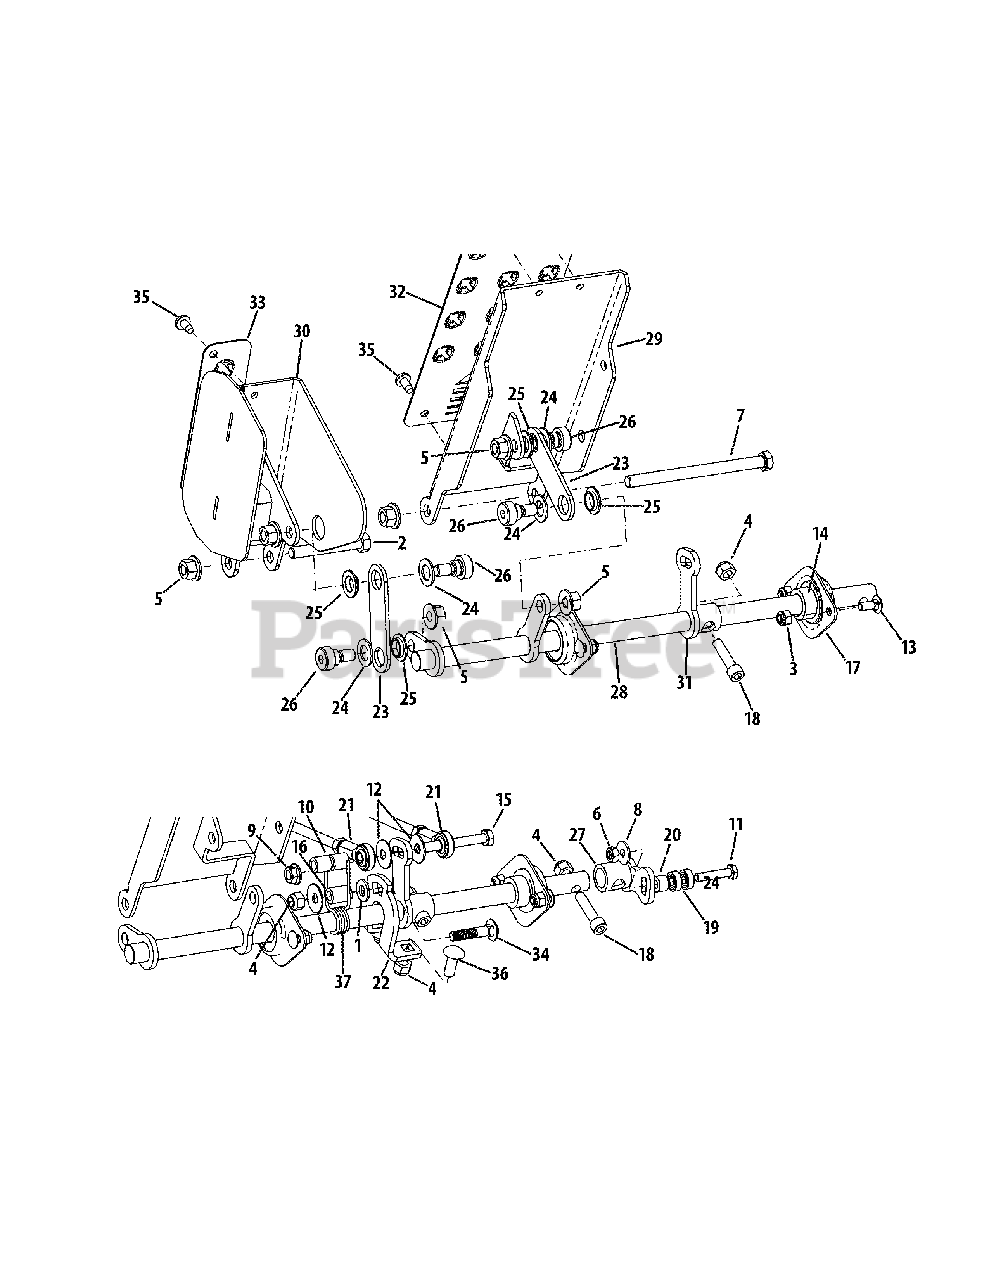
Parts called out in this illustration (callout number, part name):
1	Washer, .344 x .688 x .063
2	Hex Screw, 3/8-16 x 2.50
3	Nut, 1/4-20
4	Nut, 5/16-18
5	Flange Counter Lock Nut, 3/8-16
6	Counter Lock Nut, 1/4-20
7	Hex Screw, 3/8-16 x 5.00
8	Bell Washer, .265 x .75 x .062
9	Flange Counter Lock Nut, 5/16-18
10	Spacer, .315 x .500 x .520
11	Hex Screw, 1/4-20 x 1.25
12	Bell Washer, .325 x .930 x .045
13	Carriage Bolt, 1/4-20 x .620
14	Shaft Collar, .625 x 1.00 x .438
15	Hex Screw, 5/16-18 x 2.50
16	Spacer, .315 x .500 x .699
17	Flange Bearing
18	Screw, 5/16-18 x 1.25
19	Ball Bearing, .25 x .625 x .196
20	Spacer, .256 x .500 x .330
21	Speed Control Link Assembly
23	Pedal Control Link
24	Washer, .51 x .88 x .06
25	Flange Bearing, .502 x .875 x .180
26	Shoulder Bolt, 3/8-16 x .50 x .25
27	Lockout Hub Assembly
28	Pedal Bellcrank Assembly
29	Forward Pedal Assembly
30	Reverse Pedal Assembly
31	Control Arm Assembly
32	Forward Pedal Grip
33	Reverse Pedal Grip
34	Carriage Bolt, 5/16-18 x 1.50
35	Screw, 1/4-20 x .5
36	Carriage Bolt, 5/16-18 x .875
37	Torsion Spring, .66 x .56
